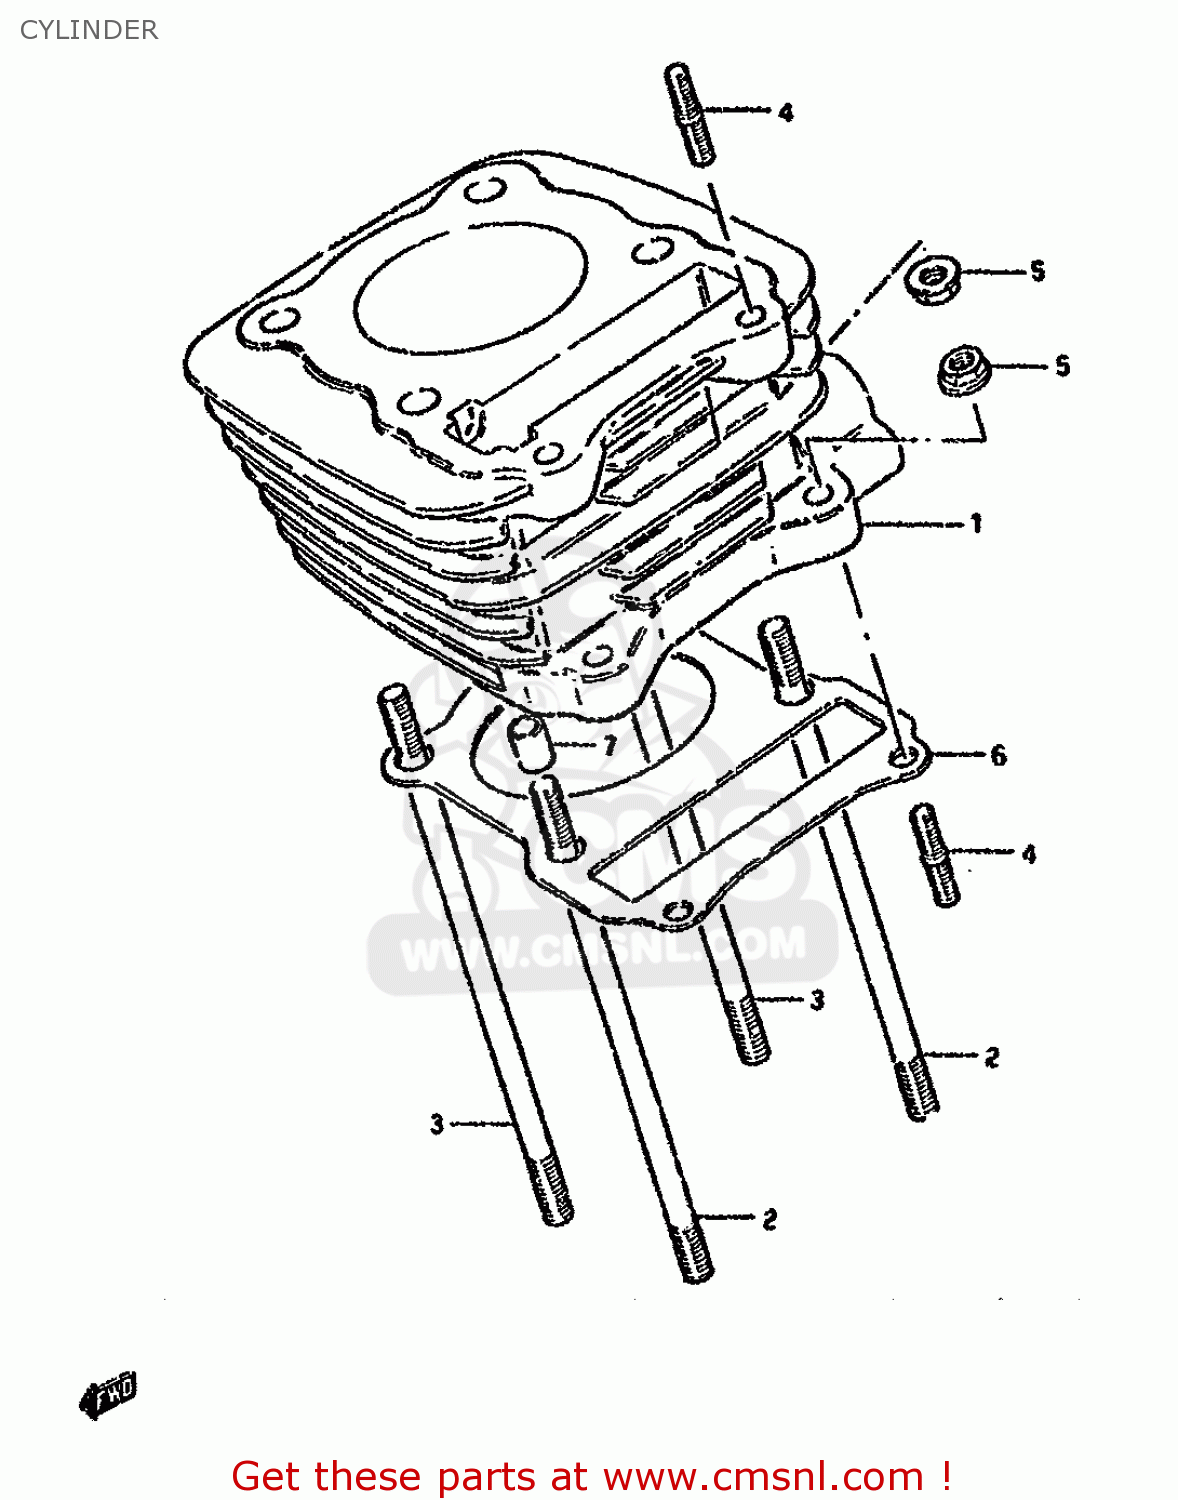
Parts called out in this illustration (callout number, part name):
1	CYLINDER
2	BOLT,STUD
3	BOLT,STUD
4	BOLT,STUD
5	NUT
6	GASKET,CYLINDER (MCA)
7	PIN
